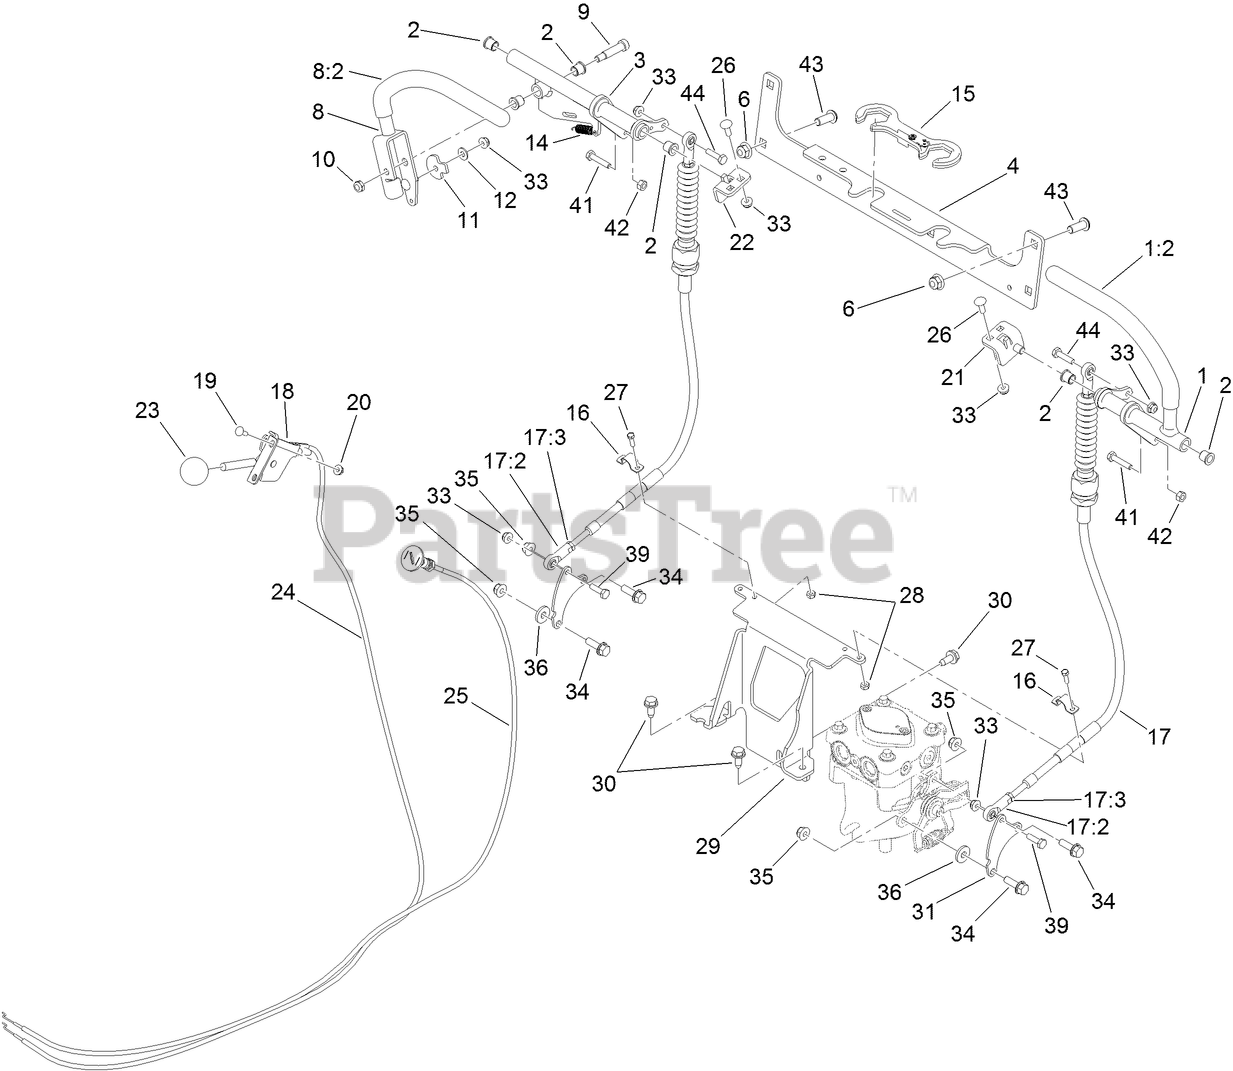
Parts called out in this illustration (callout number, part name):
1	LH LEVER ASM
2	BEARING
3	RH MOTION CONTROL ASM
4	BRACKET-CROSS
6	NUT-HF, NI
8	LEVER-MOTION, RH
9	SCREW-HSH
10	NUT-LOCK, NI
11	CAM-LEVER
12	WASHER-FLAT
14	SPRING-EXTENSION
15	LOCK-CABLE
17	CABLE ASM
17:2	ROD END-BALL JOINT
17:3	NUT-JAM
18	LEVER-CONTROL
19	BOLT-CARR
20	NUT-LOCK, FLANGE
21	LH PIVOT TAB ASM
22	RH PIVOT TAB ASM
23	KNOB-BALL
24	CABLE-THROTTLE
25	CONTROL-CHOKE, PUSH/PULL
26	BOLT-CARR
28	NUT-LOCK, NI
29	BRACKET-MOUNT, CABLE
30	SCREW-HWHTF
31	PLATE-CONTROL, PUMP
33	NUT-HF
34	SCREW-HHF
35	NUT-HF, NI
36	WASHER-FLAT
39	SCREW-HH
41	SCREW-HH
42	NUT-HEX
43	SCREW-HSBH
44	SCREW-HH
